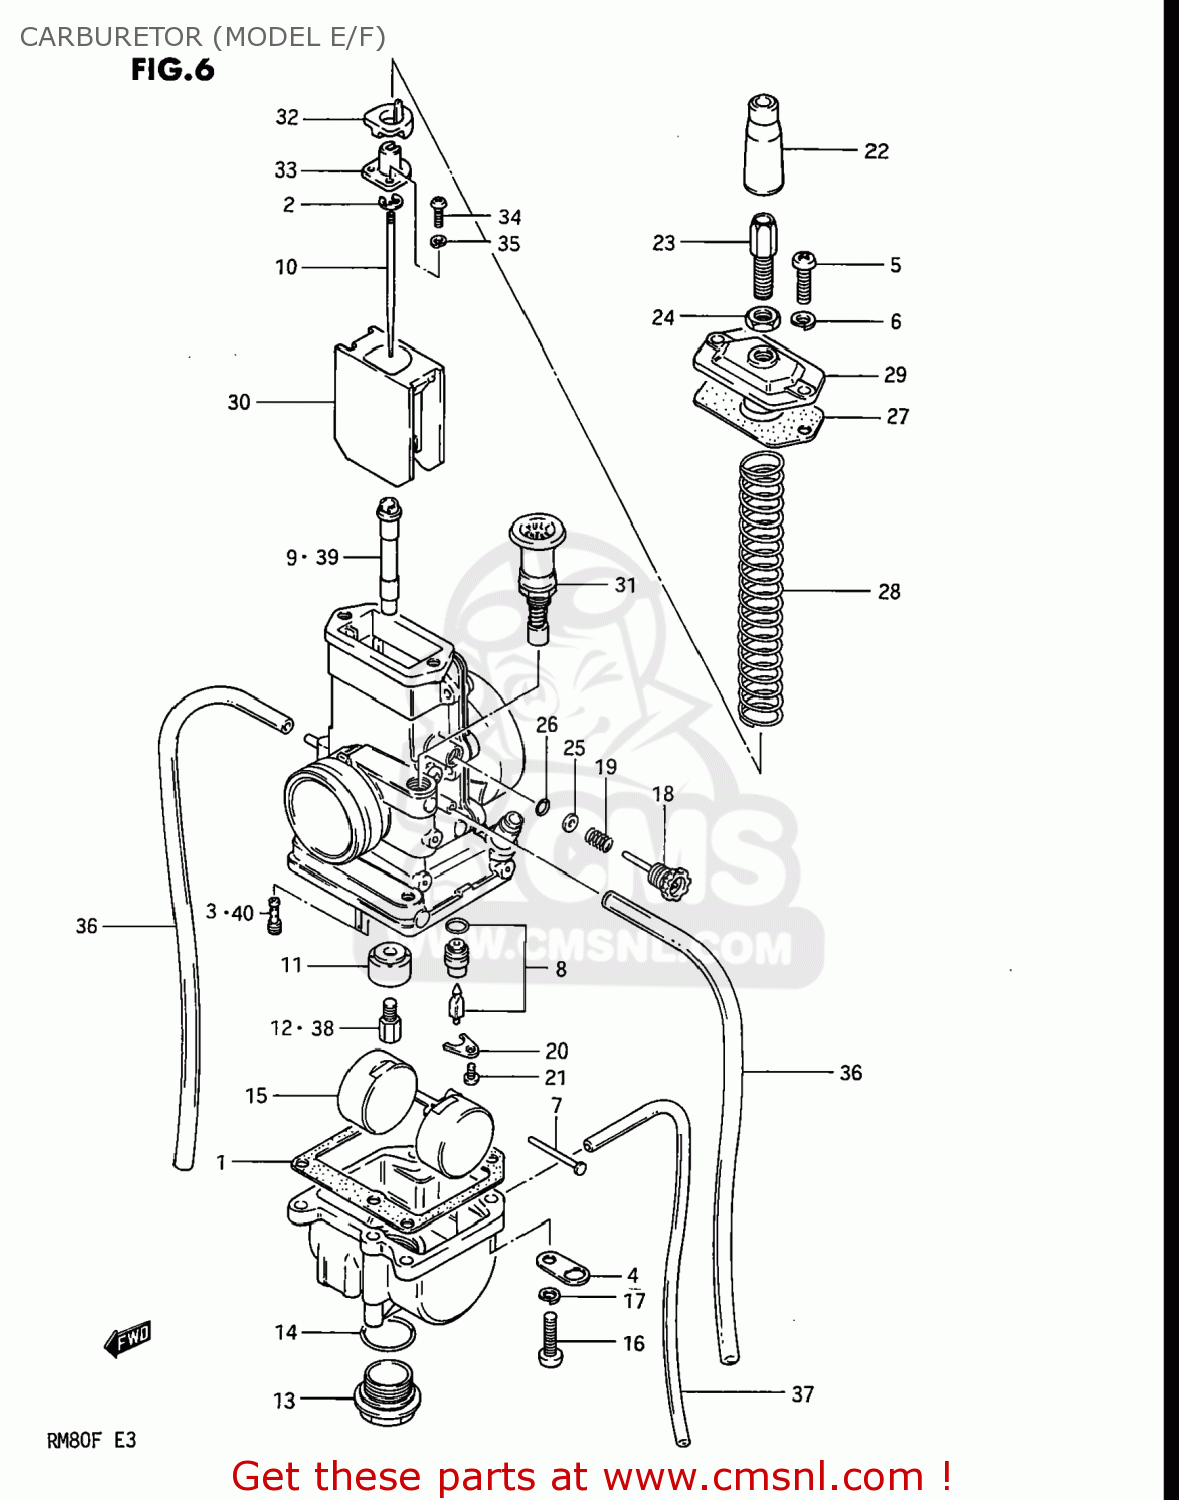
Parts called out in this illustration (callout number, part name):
1	GASKET,FLOAT CHAMBER (NAS)
2	CLIP
3	JET
4	PLATE,CARBURETOR
5	SCREW
6	LOCK WASHER
7	PIN,FLOAT
8	VALVE ASSY,NEEDLE
9	JET,NEEDLE
10	NEEDLE,JET(5DP39-4)
11	RING
12	JET,MAIN(170)
13	PLUG
14	O RING
15	FLOAT
16	SCREW
17	LOCK WASHER
18	ADJUSTER,THROTTLE STOP
19	SPRING
20	PLATE
21	SCREW
22	CAP,CABLE ADJUSTER
23	ADJUSTER,CABLE
24	NUT
25	WASHER
26	O RING
27	GASKET,CARBURETOR TOP (NAS)
28	SPRING
29	CAP,CARBURETOR TOP
30	VALVE,THROTTLE
31	VALVE ASSEMBLY,STARTER
32	RING
33	JOINT
34	SCREW
35	LOCK WASHER
36	HOSE
37	HOSE
38	JET
39	JET,NEEDLE
40	JET,PILOT(25)
